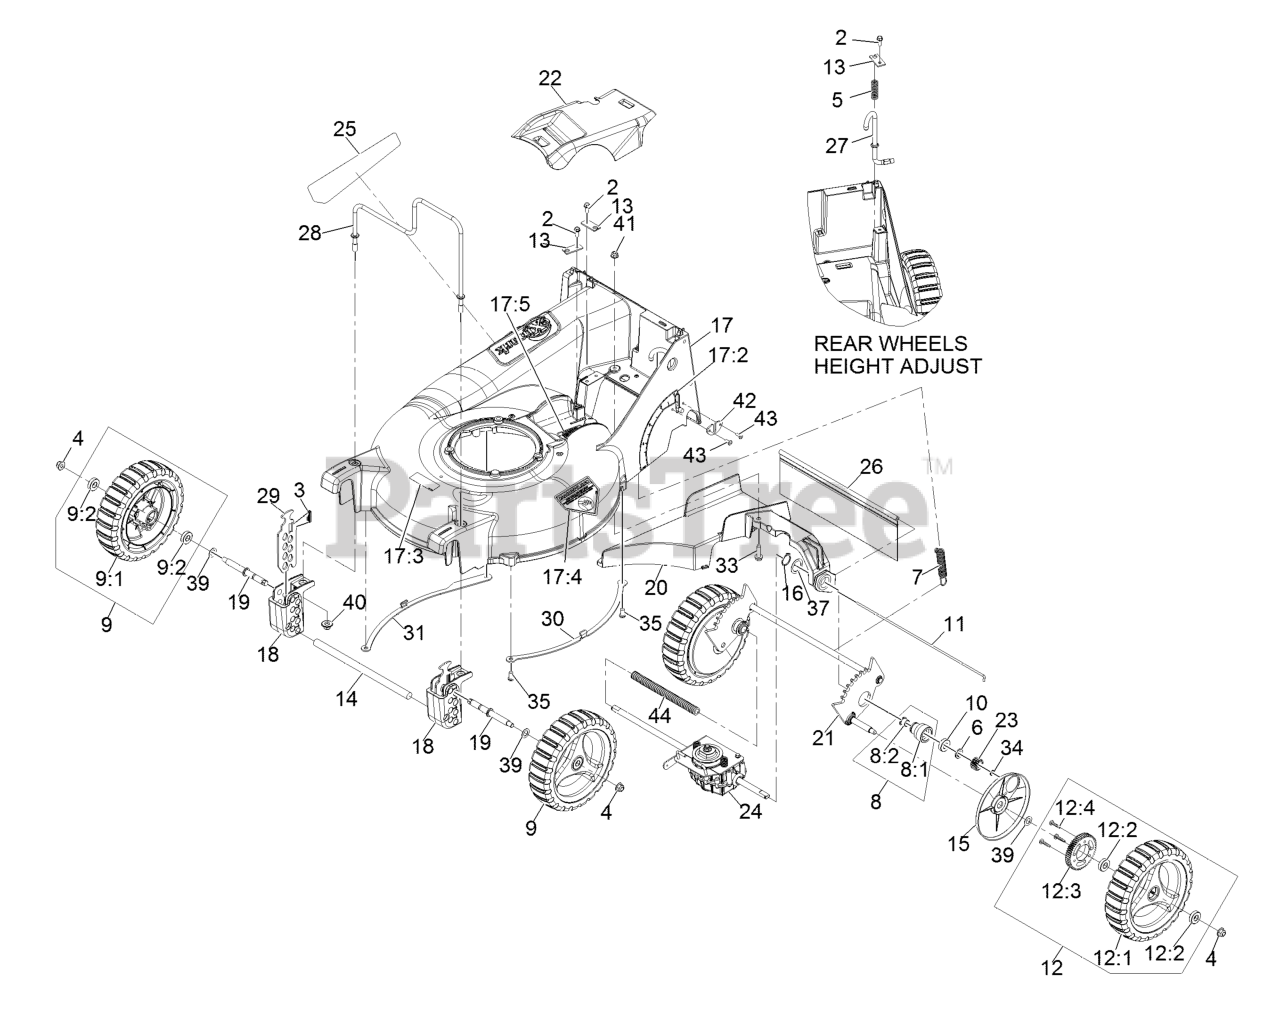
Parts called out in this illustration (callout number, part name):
2	SCREW-HWH
3	SPRING-COMPRESSION
4	NUT-HF, NI
5	SPRING-COMPRESSION
6	SPACER-BUSHING
7	SPRING-EXTENSION
8	HOUSING ASM
8:1	HOUSING-BEARING
8:2	BEARING-FLANGE
9:2	BEARING-BALL
10	BEARING-BALL
11	ROD,SHIELD
12:2	BEARING-BALL
12:4	SCREW-DRIVE
13	BRACKET,MOUNT
14	ROD,BUMPER
15	COVER,GEAR
16	RING-RETAINING
17	DECK W/DECALS
17:2	DECAL-HEIGHT OF CUT
17:3	DECAL-BLADE
17:4	DECAL-DANGER
17:5	DECAL-COVER MISSING
18	BLOCK,FRONT QUADRANT
19	AXLE-WHEEL
20	BRACKET-TRANSMISSION AND
21	WLD,REAR AXLE P21
22	COVER,BELT
24	ASM,TRANSMISSION W/BRACKE
25	DECAL-COMM 21 X-SERIES
26	SHIELD-TRAILING P21
27	ROD-HEIGHT ADJ P21
28	GUARD,ENGINE
29	PLATE, FRONT HEIGHT
33	SCREW-HWHTF
34	RING-RETAINING
35	SCREW-BHTF
39	WASHER-PLAIN
40	Nut-Nyloc 3/8-16 Flg
41	NUT-HF, NI
42	PLATE,WEAR
43	RIVET-BLIND
44	COVER-SHAFT, DRIVE
